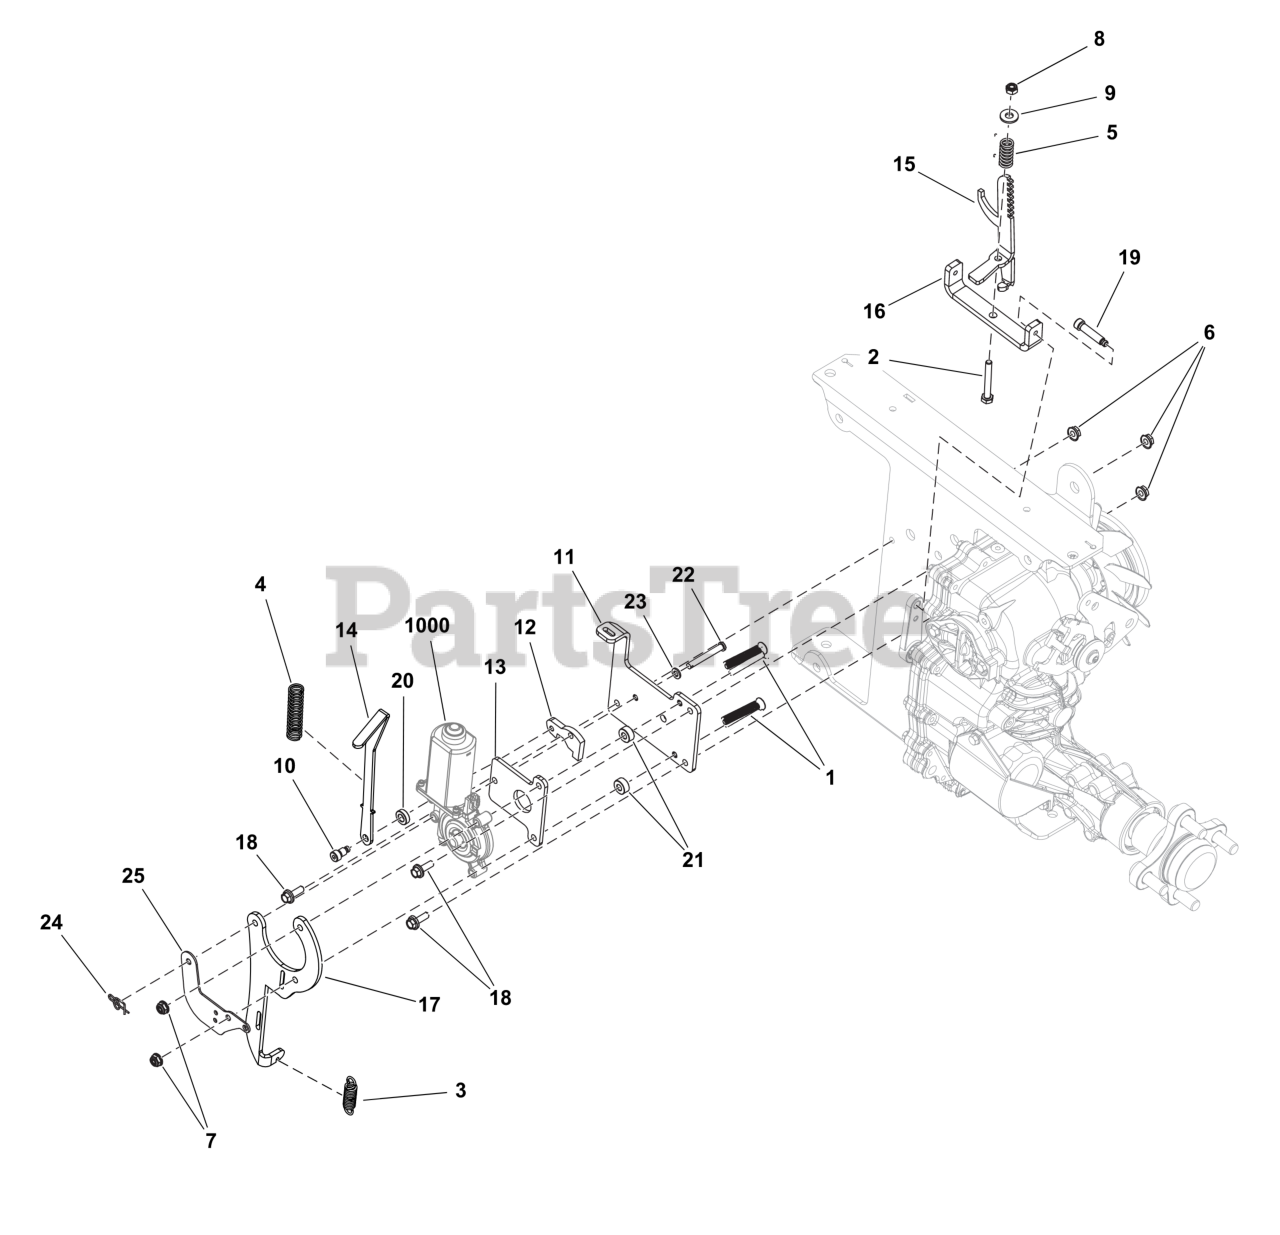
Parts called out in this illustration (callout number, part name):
3	SPRING, EXTENSION
4	SPRING, Compression
5	SPRING, COMPRESSION
8	NUT, 1/4-20 HEX NYLON
15	BRACKET, BRAKE
16	ARM, Lever
17	PLATE, SWITCH
20	SPACER, .328 X .62 X .200, CZ
21	SPACER, .265 X .62 X .290, CZ
22	PIN, CLEVIS, 1/4 X 1 7/8, PLATED
23	WASHER, M6 FLAT ZP
24	COTTER PIN, 3/8
25	PLATE, BRAKE SWITCH SPACER - BLK
1000	Refer to: Electrical Group
